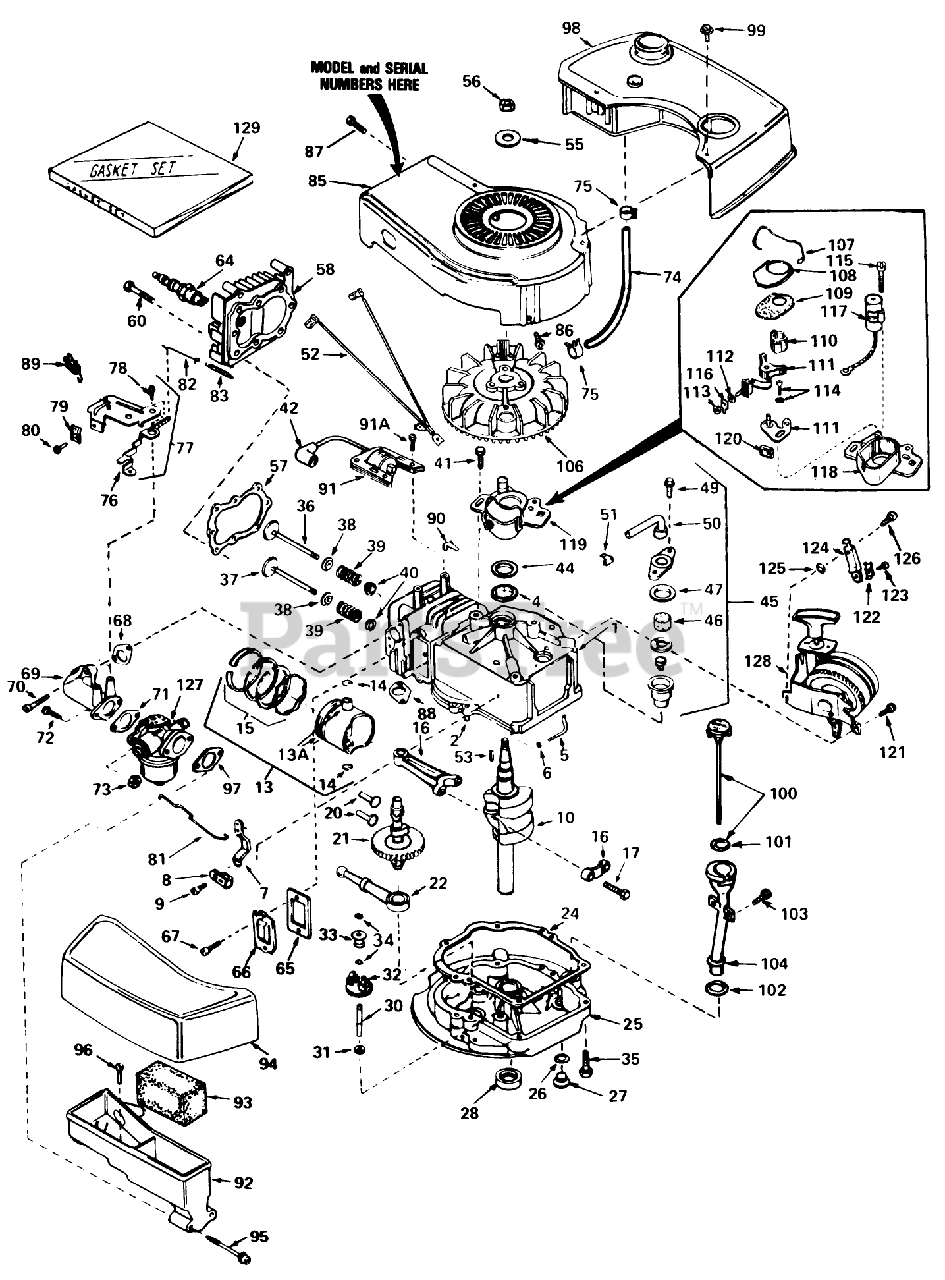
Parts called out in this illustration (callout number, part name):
1	Cyiinder Assy. (Incl. Ref. #2, 4 105)
2	Pin-Dowel
4	Seal-Oil
5	Rod, Governor (Incl. No. 36)
6	Washer-Flat
7	Governor Lever
8	Clamp-Lever, Governor
9	Screw
10	Crankshaft
13	Piston, Pin Ring Assy. (Std.)(Incl. Ref. #13A, 14 15)
13	Piston,Pin Ring Assy. (.010 over-size)(Incl. Ref. #13A, 14 15)
13	Piston, Pin Ring Assy. (Incl. Nos. 13A, 14 15)(.020 oversize)
13A	Piston Pin Assy. (Incl . Ref. . #14) (Std.)
13A	Piston Pin Assy. (Incl. Ref. #14) (.010 Oversize)
13A	Piston Pin Assy. (.020 oversize) (Incl. Ref. #14)
14	Ring-Retaining, Piston Pin
15	Ring Set Piston (Std.)
15	Ring Set Piston (.010 Oversize)
15	Ring Set Piston (.020 Oversize)
16	Rod Assy., Connecting (Incl. Ref. #17)
17	Bolt-Rod, Connecting
20	Lifter-Valve
21	Camshaft(Mech.Comp. Release)
22	Oil Pump ASM
24	Gasket, Mounting
25	Flange Assy., Mounting (Incl. Ref. #26thru 30)
26	Gasket-Oil Drain
27	Plug Oil Drain
28	Seal Oil
30	Shaft-Governor
31	Washer-Flat
32	Governor Gear ASM
33	Spool-Governor
34	Ring-Retaining
35	Screw (1/4-20 x 1-1/4)
36	Valve, Intake (Incl. Ref. #38, 39 40) (Std.)
36	Valve, Exhaust (1/32" Oversize) (Incl. Nos. 8, 9 10)
37	Valve, Exhaust (Standard) (Incl. Nos. 8, 9 10)
37	Valve, Exhaust (1/32" Oversize) (Incl. Nos. 8, 9 10)
38	Cap-Upper Valve Spring
39	Spring-Valve
40	Cap-Valve, Spring
41	Screw
42	18 Cover Spark Plug
44	Gasket Stator
45	Breather Assy. (Incl. Ref. #46 thru 51)
46	Element-Breather
47	Gasket-Breather
49	Screw (10-24 x 9/16)
50	Tube, Breaker
51	Clip, Breather
52	Wire Ground
53	682488 LB GRASS HI-
55	Washer-Belleville
56	Nut-Flywheel
57	63573 GIL 42 SNWTHW
58	Head-Cylinder
60	Screw
64	Plug, Spark (J17LM or equiv.)
64	Plug, Spark (Champion RCJ-8)
65	Gasket-Breather
66	Cover-Valve
67	Screw
68	Gasket-Intake
69	Pipe, Intake (Incl. No. 68)
70	Screw (1/4-20 x 1)
71	Gasket-Carburetor
73	Nut and Lock Washer (1/4-28)
74	Line-Fuel
75	Clamp-Line, Fuel
76	Lever Control
77	Control Assy., Speed (Incl. Nos, 76, 78 89)
78	Screw, Hex Washer Hd Shoulder Self-Tap
79	Conduit
80	Screw (10-32 x 3/8)
81	Link-Throttle
82	Link Governor Spring
83	Spring Governor
85	Housing Blower
86	Screw
87	Screw (10-24 x 9/16)
88	Gasket Exhaust
89	Terminal
90	Clip-Wire
91	Lamination Coil Assy. (Incl. No. 42)
91A	Screw
92	Body Air Cleaner
93	Filer, Air
94	Cove, Air Cleaner
95	Screw Fil Hd.
96	Screw, Hex Hd.
97	Gasket-Air Cleaner
98	Tank, Fuel
99	Screw (10-32 x 35/64)
100	Dipstick, Oil (Incl. Ref. #101)(Twist Lock)
101	O-Ring
102	Gasket
103	Screw (10-32 x 1/2)
104	Tube-Oil Fill
106	FIywheel
107	Spring Breaker Box
108	Cover-Dust
109	Gasket-Dust Cover
110	Cam-Breaker
111	Breaker Assy.
112	Washer
113	DECAL
114	Breaker Screw
115	Condenser Screw
116	Terminal, Ground
117	Condenser
118	Stator Plate
119	Stator Plate Assy. (incl. Nos. 107, 111 thru 118 120)
120	Felt,Cam Wiper
121	Screw (1/4-20 x 1/2)
122	Conduit
123	Screw (10-32 x 3/8)
124	Bracker
125	Washer
126	Screw (1/4-20 X 5/8)
127	Carburetor (Incl. Ref. #71 )
128	Starter
129	Gasket Set
